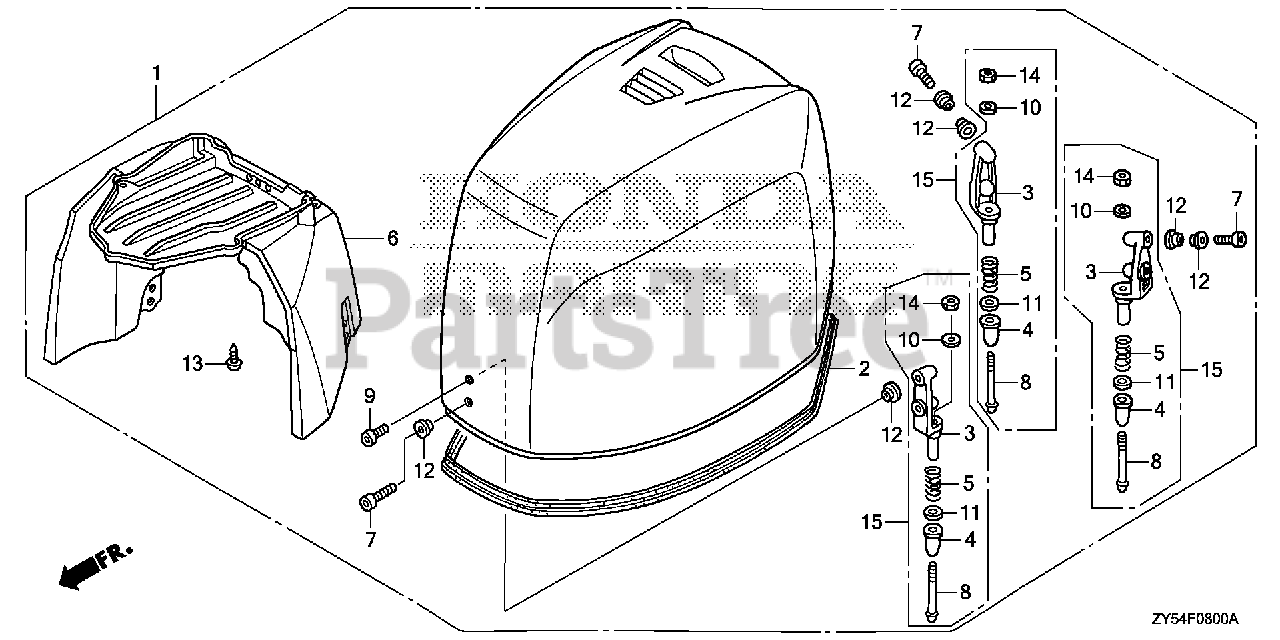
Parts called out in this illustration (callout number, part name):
1	COVER ASSY., ENGINE *NH282MU* (OYSTER SILVER METALLIC-U)
2	SEAL, ENGINE COVER
3	BRACKET, HOOK
4	DAMPER, HOOK
5	SPRING, LOCK ADJUSTER
6	GUIDE, ENGINE COVER AIR
7	BOLT, SOCKET (6X20)
8	BOLT, COVER LOCK
9	BOLT, SOCKET (6X16)
10	WASHER, PLAIN (6MM)
11	WASHER, PLAIN (12MM)
12	COLLAR, DISTANCE (6.5X9X3)
13	SCREW, TAPPING (4X10)
13	SCREW, TAPPING (4X12)
14	NUT, HEX. (6MM)
15	HOOK KIT, COVER
